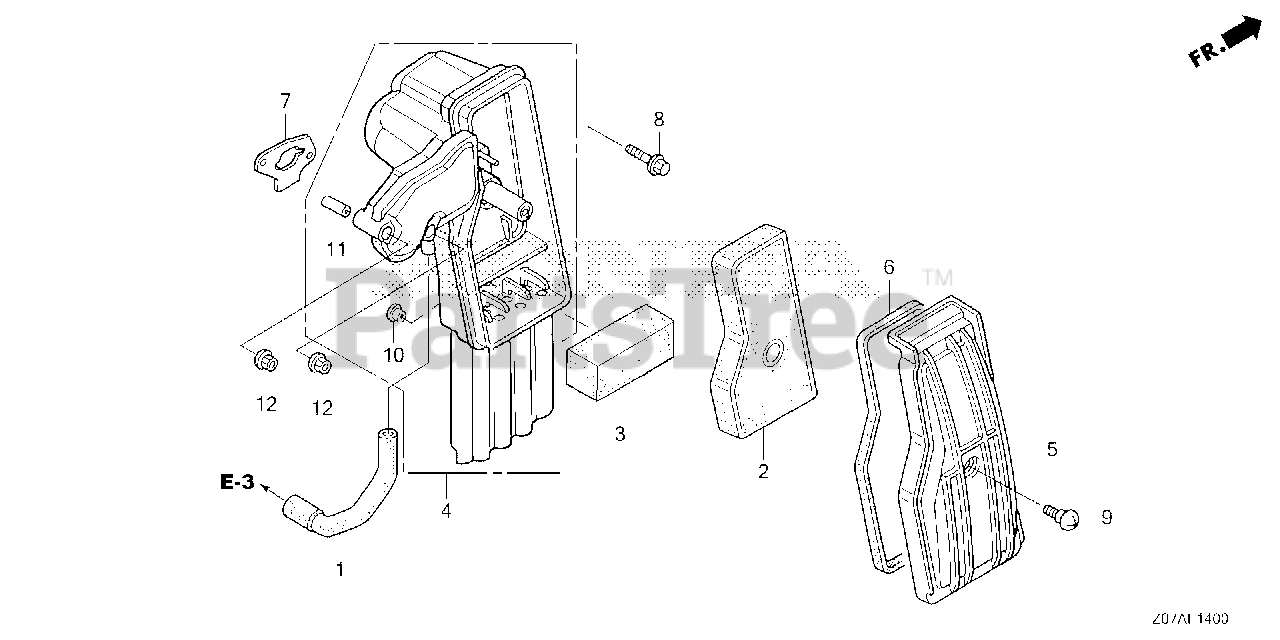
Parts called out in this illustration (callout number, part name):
1	TUBE, BREATHER
2	ELEMENT, AIR CLEANER
3	FILTER (OUTER)
4	HOUSING, AIR CLEANER
5	COVER, AIR CLEANER
6	SEAL A, AIR CLEANER COVER
7	GASKET, AIR IN. JOINT
8	BOLT, FLANGE (5X16)
9	SCREW, SPECIAL (6X16)
10	COLLAR, REFLECTOR SETTING
11	COLLAR, AIR CLEANER
12	NUT, FLANGE (5MM)
